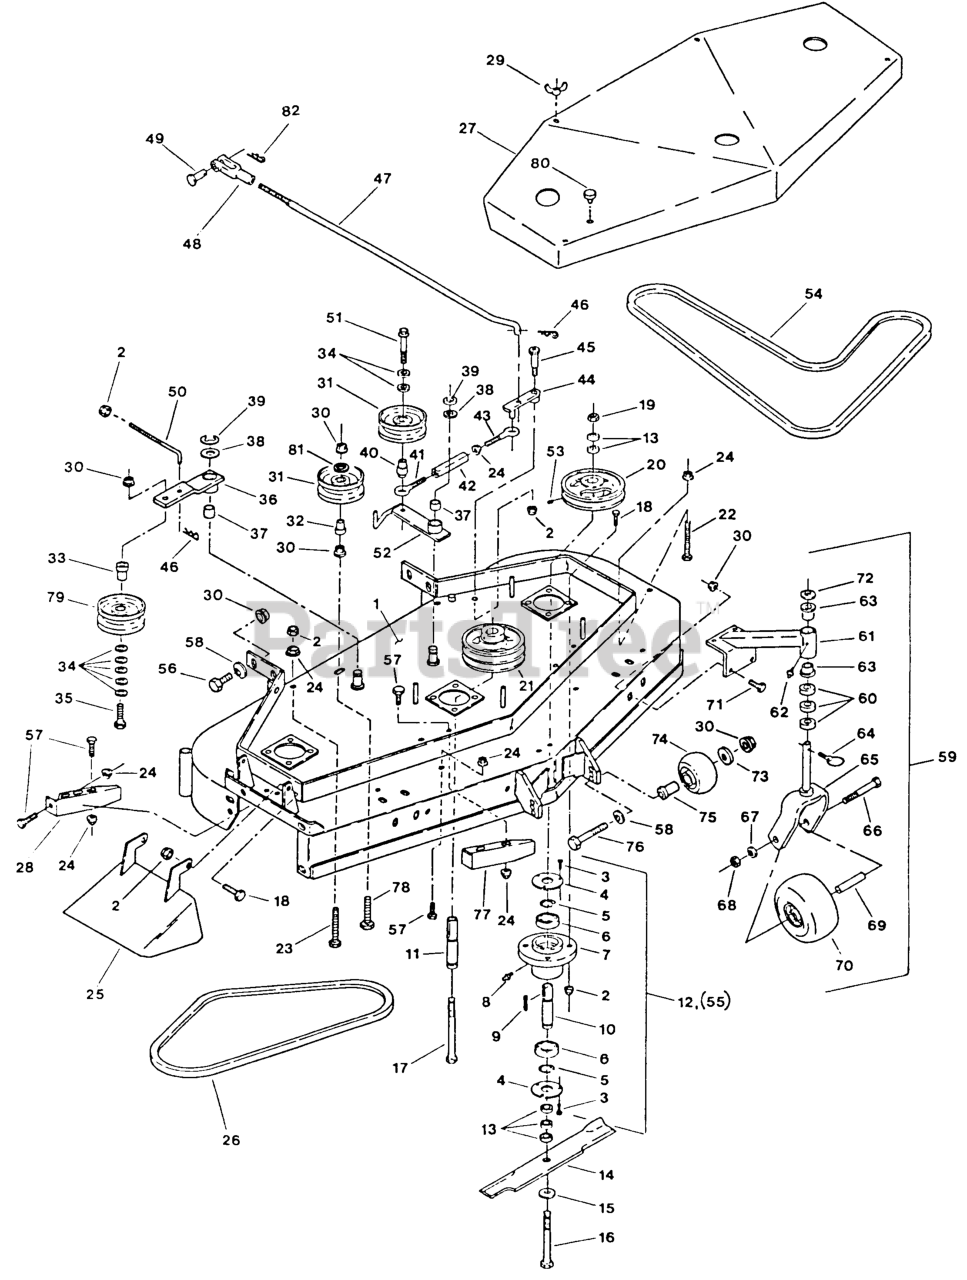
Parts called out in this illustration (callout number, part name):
3	SCRWMACH PHS
4	CAP,CUTTER HOUSING
5	RING,RETNG WLDS 5108-100
7	HOUSING,CUTTER
10	SPINDLE,CUTTER
12	HOUSING,CUTTER COMPLETE
17	SCREW-CAP, HH
20	PULLEY,CAST IRON
22	BOLT,TAP HH
23	BOLTTAP HH
25	WLD,CHUTE DISCHARGE
28	WLD, DISCHARGE BAFFLE
33	BUSHING-IDLER
36	ARM WLDMNT W/BUSHING
37	BEARING,POWDERED METAL
38	WASHER-SPINDLE
40	BUSHING-ENGAGEMENT
41	EYEBOLT-THREAD, LH
42	BODY-TURNBUCKLE
43	EYEBOLT-THREAD, RH
45	BOLT,SHLDR KSKH
46	PIN-COTTER
47	LINKAGE
48	YOKE-ADJUSTABLE
49	PIN-CLEVIS
50	LINKAGE
53	SCREW-SET
54	BELT,BLADE DRIVE 48
55	HOUSING,CUTTER COMPLETE
60	SPACER-CASTER
63	BEARING-FLANGED
72	WASHER-FLAT
74	ROLLER-SCALP, ANTI
75	BUSHING-ROLLER
78	BOLT,TAP HH3/8-16X2-1/4
79	IDLER,PULLEY
